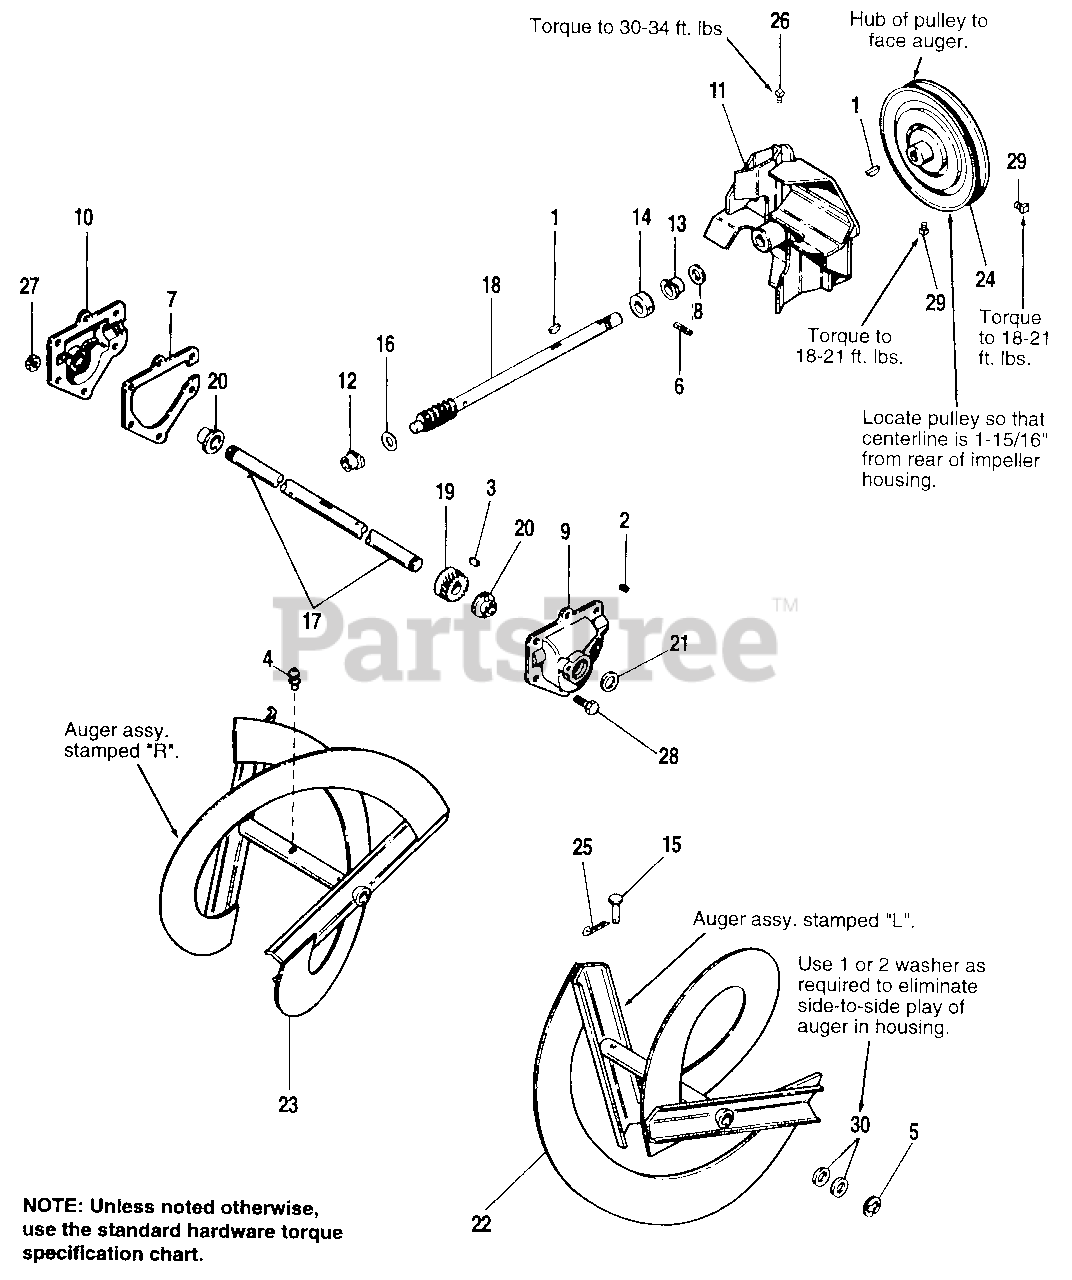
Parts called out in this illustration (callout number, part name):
1	KEY, Woodruff, 3/16 x 3/4
2	PLUG, Pipe, 1/8-NPT
3	KEY, Woodruff
4	GREASE FITTING
5	RING, Retaining
6	PIN, Drivelok, 3/16 x 1-1/2
9	* GEAR CASE ASSY., LH (Incl. Ref. No. 20, Qty. 1)
10	* GEAR CASE ASSY., RH (Incl. Ref. No. 20)
11	IMPELLER ASSY.
14	COLLAR, Thrust
15	PIN, Shear
16	WASHER, Thrust
17	AUGER, Shaft
22	AUGER ASSY., LH (Incl. Ref. No. 4, Qty. 1)
23	AUGER ASSY., RH (Incl. Ref. No. 4, Qty. 1)
24	PULLEY, Input, Auger
25	PIN, Cotter, 3/4
26	SETSCREW, Sq. Hd., 3/8-16 x 1/2
27	NUT, Lock, 1/4-20
28	CAPSCREW, Hex, 1/4-20 x 7/8
29	SETSCREW, Sq. Hd., 5/16-18 x 1/2
30	WASHER
